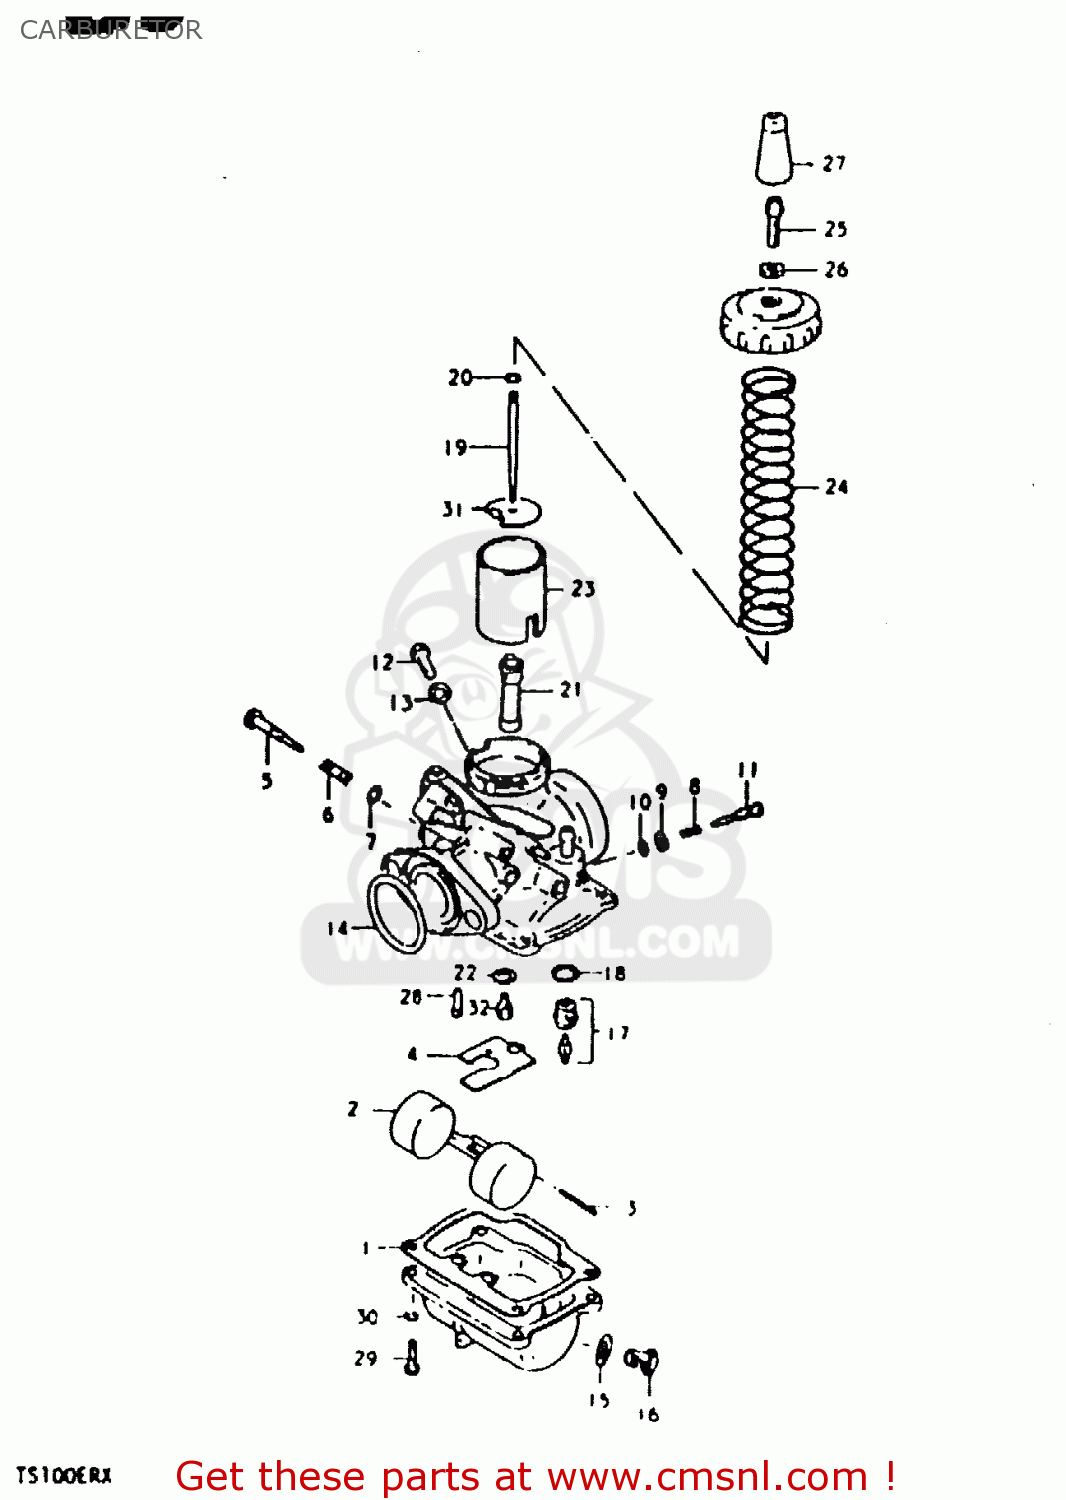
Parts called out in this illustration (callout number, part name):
1	GASKET,FLOAT CHAMBER (NAS)
2	FLOAT
3	PIN,FLOAT
4	PLATE
5	SCREW,THROTTLE STOP
6	SPRING,PILOT
7	O-RING
8	SPRING
9	WASHER,PILOT AIR SCREW
10	O RING
11	SCREW,PILOT AIR
12	BOLT
13	GASKET,THRO VALVE INSPECTION (NAS)
14	O RING
15	GASKET,DRAIN,PLUG (NAS)
16	PLUG
17	VALVE ASSEMBLY,NEEDLE
18	GASKET,VALVE SEAT (NAS)
19	NEEDLE,JET
20	CLIP
21	JET,NEEDLE
22	WASHER
23	VALVE,THROTTLE
24	SPRING, THROTTLE VALVE
25	ADJUSTER,CABLE
26	NUT
27	CAP
28	JET
29	SCREW
30	LOCK WASHER
31	SEAT,THROTTLE VALVE SPRING
32	JET,MAIN 85
